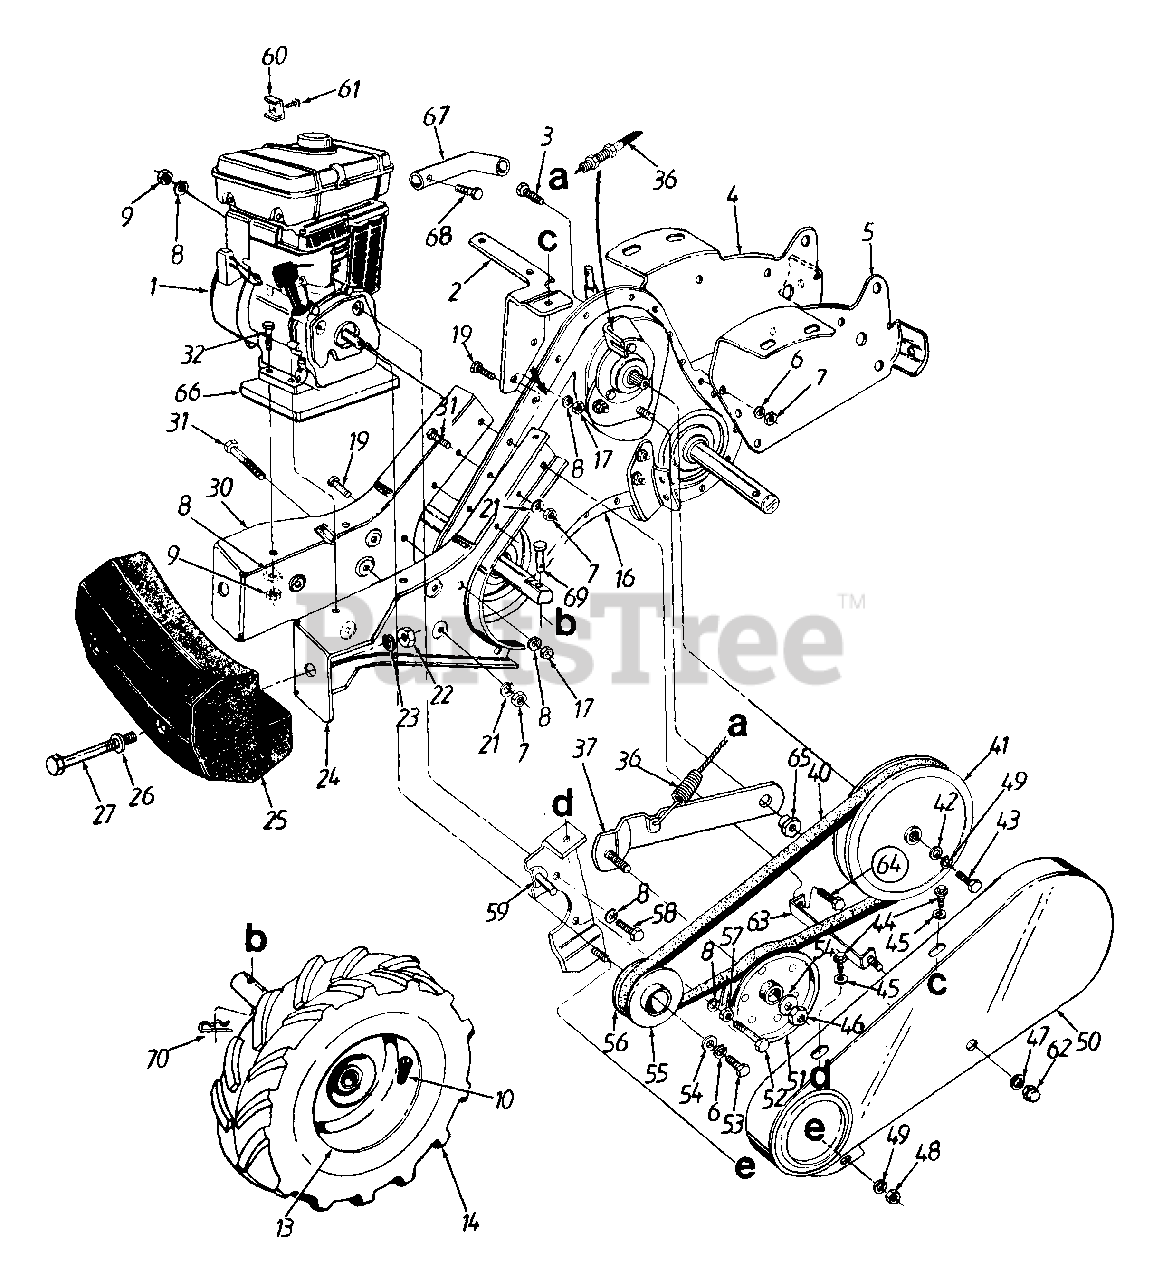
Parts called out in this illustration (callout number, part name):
1	Engine
4	Tine Shield Mtg. Brkt. - R.H.
7	Hex Nut 3/8-16 Thd.
8	L-Wash. 5/16" I.D.
9	Hex Nut 5/16-18" Thd.
10	Air Valve
10	Hex Bolt 5/16-24 x .62" Lg.
10	Bell-Wash. .345" I.D. x .88"
16	Gear Case Ass'y. Comp.
17	Hex Nut 5/16-18 Thd.
19	Hex Bolt 5/16-18 x .75" Lg.
21	L-Wash. 3/8" I.D. - H.D.
22	Hex Nut 1/2-13 Thd.
23	L-Wash. 1/2" I.D.
26	Fl-Wash. .510" I.D. x 1.0"
27	Hex Bolt 1/2-13 x 5.00" Lg.
32	Hex Bolt 5/16-18 x 2.75"
36	Clutch Control Cable 46" Lg.
37	Idler Bracket Ass'y.
40	V - Belt
41	Fl-Pulley 8" O.D.
42	Fl-Wash. 1/4" I.D. x .93" O.D.
43	Hex Bolt 1/4-28 x .75" Lg.
44	Hex Wash. Hd. S-Tap Scr. 1/4-20 x .50" Lg.
45	Fl-Wash. .281" I.D. x .625"
46	Hex Cent. L-Nut 3/8-24 Thd.
47	Fl-Wash. .266" I.D. x .625" O.D.
48	Hex Nut 1/4-2O Thd.
49	L-Wash. 1/4" I.D.
51	Fl-Idler w/Flanges 3.75" O.D.
52	Hex Bolt 5/16-24 x 1.75"
53	Hex Bolt 3/8-24 x 1.00" Lg.
54	Fl-Wash. 3/8" I.D. x 1.00"
55	Outer Engine Pulley Half
56	Inner Engine Pulley Half
57	Hex Nut 5/16-24 Thd.
58	Hex Bolt 5/16-24 x .62" Lg.
59	Belt Keeper Ass'y.
60	Casing Clamp
61	Hex Sems Scr. #10-32 x .62"
62	Hex Cap Nut 1/4-28 Thd.
63	Belt Cover Brkt. Ass'y.
64	Hex Bolt 5/16-18 x 1" Lg. (Gr. 5)
65	Shld. Nut
66	Engine Spacer Block
67	Outlet Pipe
68	Hex Wash. Hd. AB-Tap Scr. #8 x .5" Lg.
69	Clevis Pin
70	Hairpin Clip
